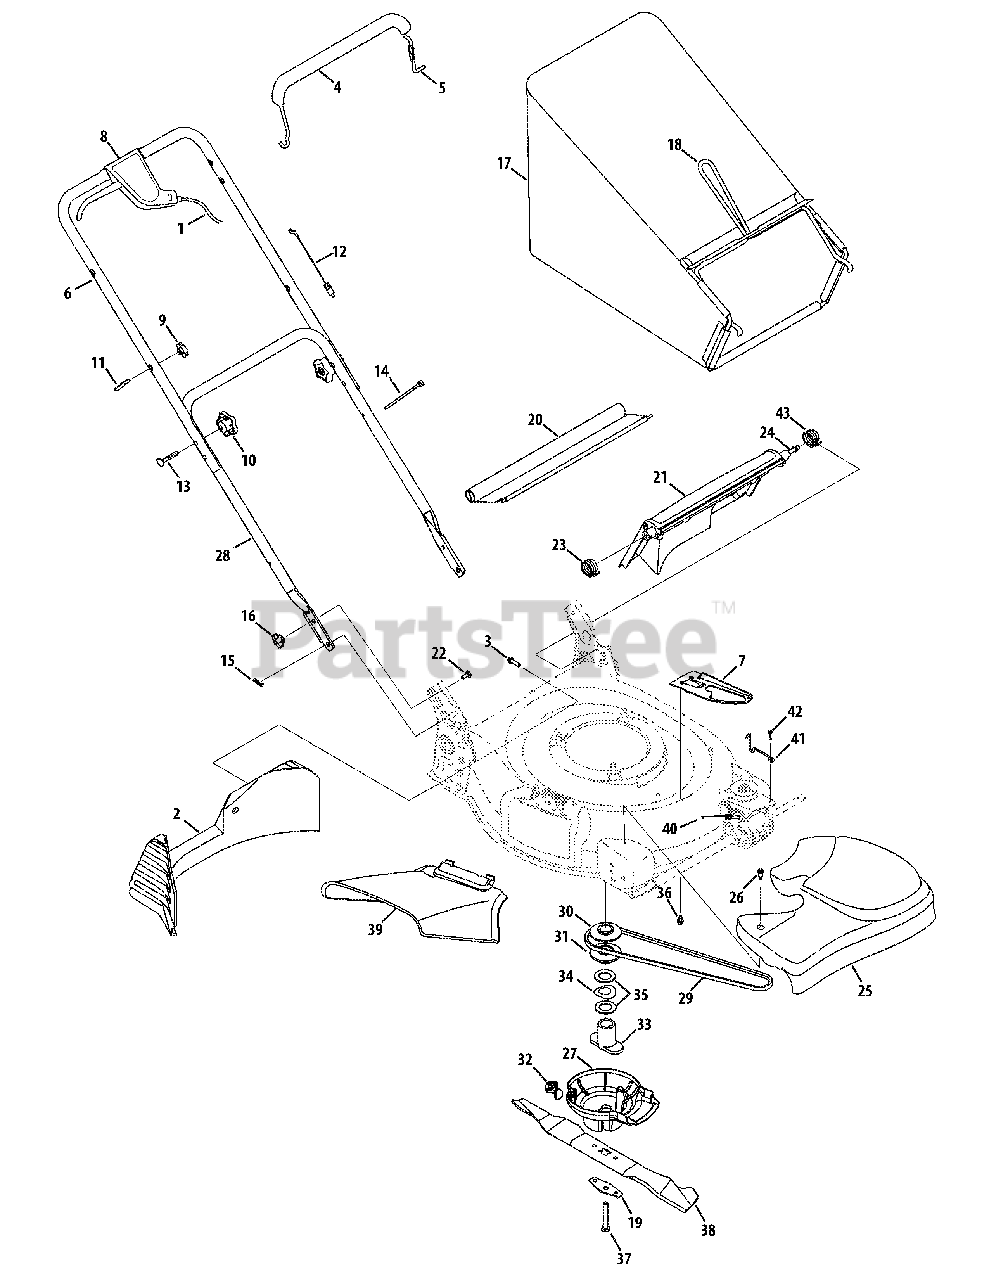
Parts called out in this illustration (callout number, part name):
1	Variable Speed Cable
2	Rear Baffle 21'' Rd
3	Screw, 1/4-15 x 1.000
4	Deluxe Bail Cover
8	Control Lever Assembly
9	Handle Knob
10	Star Knob
12	Control Cable - 40''
13	Carriage Bolt, 5/16-18 x 2.0
14	Cable Tie
15	Cotter Pin
16	Wing Nut
17	Grass Bag Assembly
19	Blade Bell Support
20	Rear Trailing Shield
21	Rear Discharge Door
22	Carriage Bolt, 1/4-20
23	Torsion Spring - RH
25	Transmission Cover (Black)
26	Shoulder Screw, # 12-24
27	Engine Baffle
29	V-Belt
30	Upper Pulley Half, 25mm x 2.62
31	Lower Pulley Half, 25mm x 2.62
32	Baffle Bracket
33	Blade Adapter
34	Spacer Washer
35	Flat Washer
36	Screw, 1/4-14 x .625
37	Hex Screw, 3/8-24 x 2.50
38	21'' Mulching Blade
39	Side Discharge Chute
40	Extension Spring
41	Belt Keeper Wire
42	Torx Screw
43	Torsion Spring - LH
